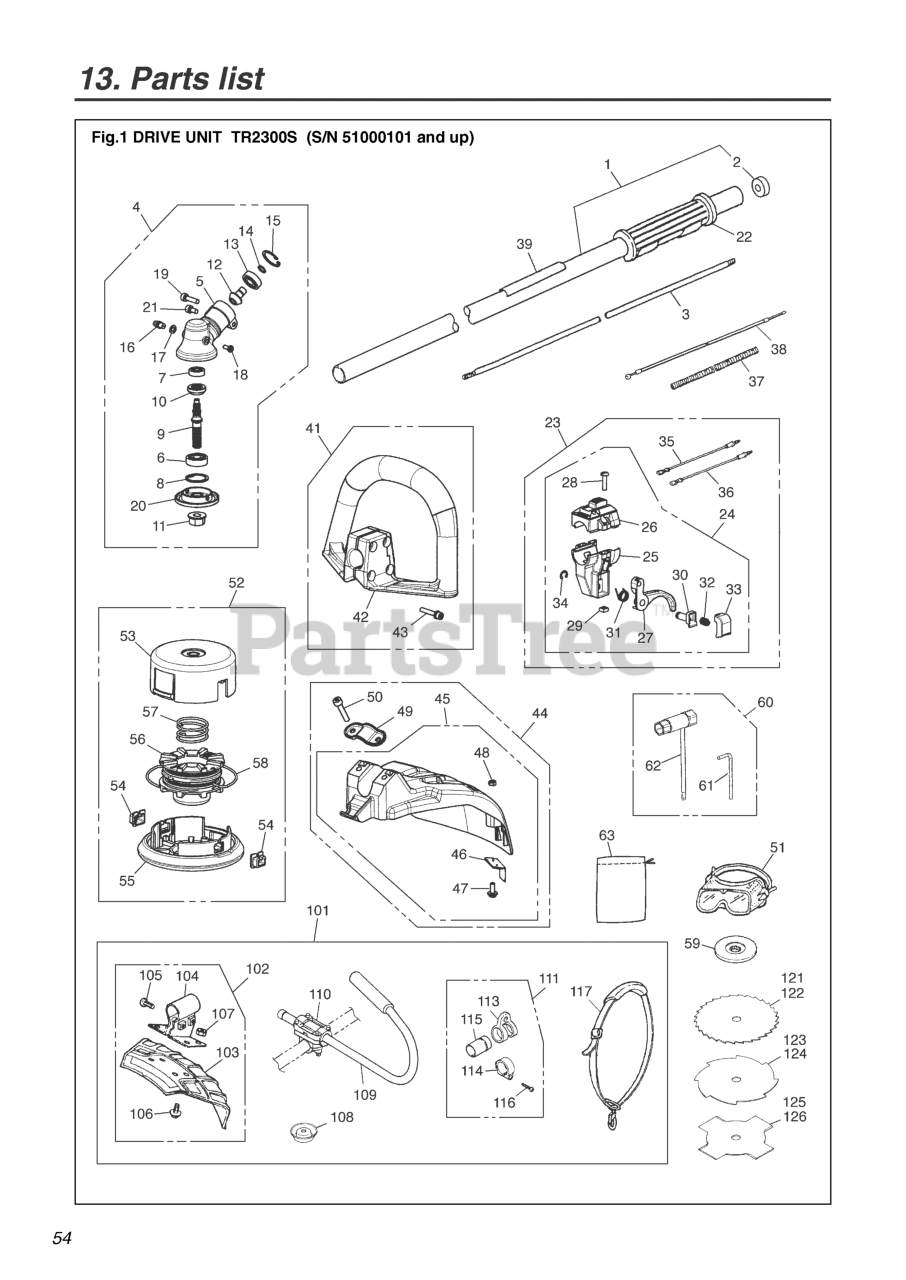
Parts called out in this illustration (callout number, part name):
1	PIPE COMP.
2	SEAL
3	SHAFT (RPLS -12212)
4	GEARCASE ASSY.
5	GEARCASE
6	BEARING
7	BEARING (RPLS T3300-13521)
8	RING, SNAP, M26 X 1.2
9	SHAFT
10	GEAR
11	NUT
12	PINION
13	BEARING (RPLS T3300-13531)
14	RING, SNAP (RPLS T3300-13330)
15	RING, SNAP, M24 x 1.2
16	FITTING, GREASE
17	WASHER, M6 X .8
19	BOLT (RPLS 2850-14220)
20	HOLDER (A)
21	BOLT
22	GRIP
23	LEVER ASSY. (RPLS. T3002-12203
24	LEVER ASSY (RPLS. 6110-14412)
26	COVER (USE 848-8RA-0340)
27	FLEX, TRIGGER
35	CORD (A), BLACK
36	CORD (B), RED
37	TUBE
38	CABLE COMP (RPLS 1633-83100)
39	PLATE, NAME
41	HANDLE ASSY. (REPLACES -14001)
42	HANDLE T
43	SCREW
44	GUARD ASSY.
45	GUARD ASSY.
46	BLADE
47	SCREW
48	NUT
49	CLAMP (REPLACES 5807-24120)
50	BOLT, TORX
51	GOGGLE
52	TAP HEAD COMP.
53	CASE (REPLACES -15111)
54	EYELET
55	COVER (REPLACES -15131)
56	HOLDER, CORD (REPLACES-15141)
57	SPRING
58	CORD
59	HOLDER (B)
60	TOOL SET
61	BAR
102	GUARD ASSY.
103	GUARD (ACC.)
105	BOLT
106	SCREW
107	NUT, M6 X 5
108	COVER
109	HANDLE, J
110	BRACKET ASSY (REPLACES -14100)
111	HANGER ASSEMBLY
113	HANGER
114	CLAMP
115	SLEEVE
116	SCREW, M5 x 25
117	STRAP ASSY.
121	BLADE, 9
122	BLADE, 9
123	BLADE, 8
124	BLADE, 9
125	BLADE, 8
126	BLADE, 9
